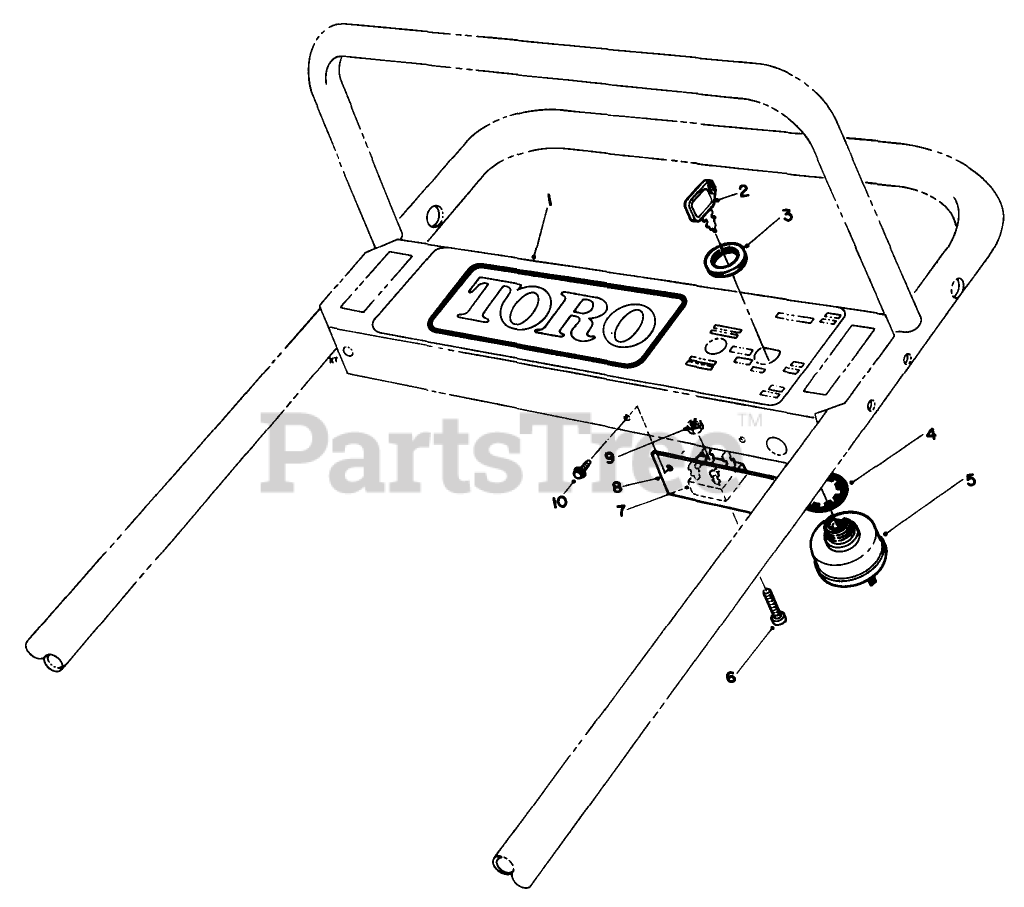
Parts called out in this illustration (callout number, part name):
2	KEY-IGNITION
3	NUT-HH
4	WASHER-LOCK
5	SWITCH-STARTER
6	SCREW-HWH
7	RECTIFIER-BRIDGE
8	BOTTOM PANEL *B
9	NUT-LOCK, NI
10	SCREW-HWHTF
